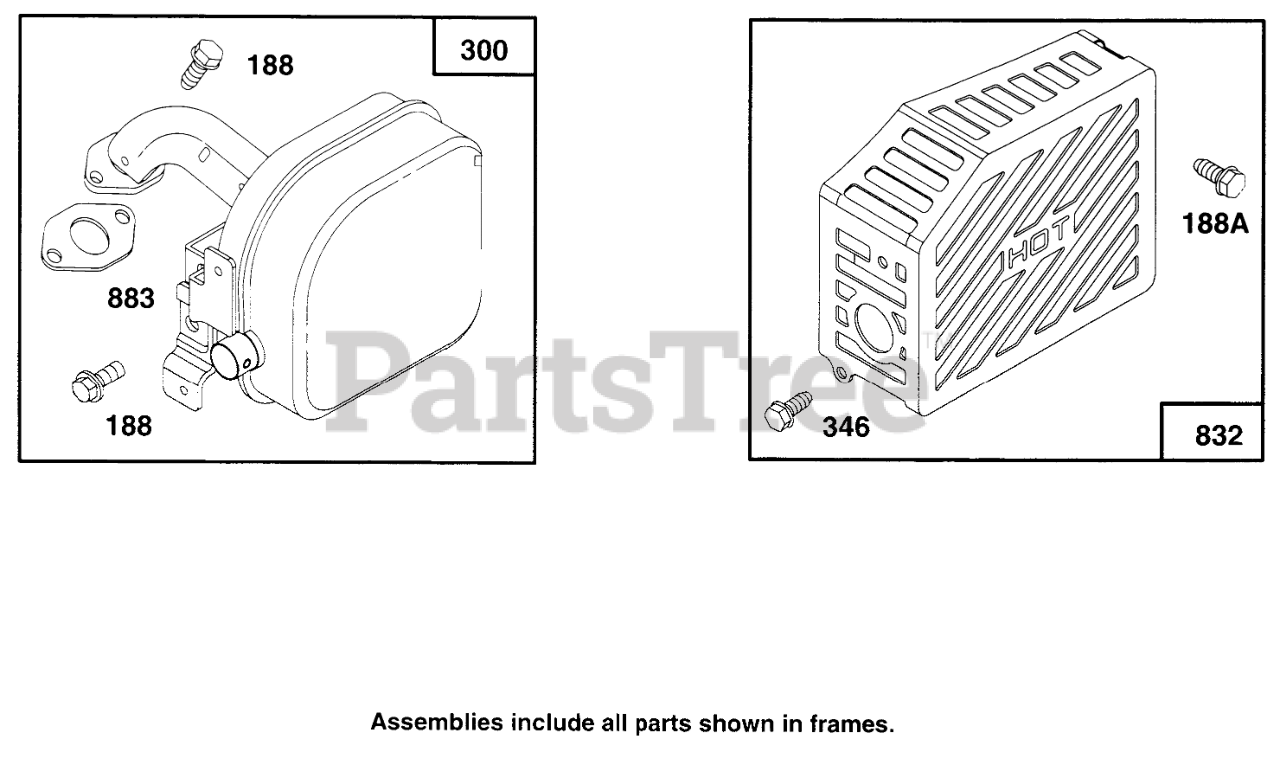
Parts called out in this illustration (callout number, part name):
188	Screw-Cap
188A	SCREW - HEX HEAD
300	MUFFLER - EXHAUST
346	Screw-Hex
832	Guard-Muffler
883	EXHAUST GASKET
